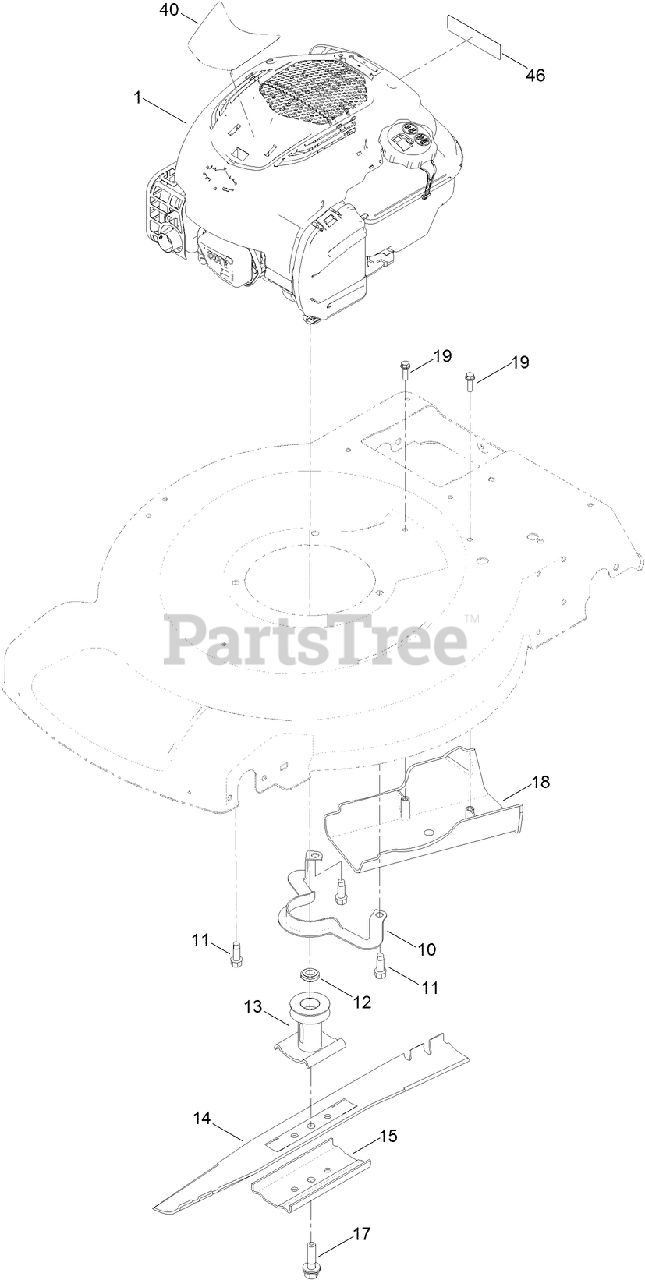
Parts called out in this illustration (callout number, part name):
10	GUIDE-BELT
11	SCREW-TAPTITE
12	SPACER-DRIVER
13	DRIVER-BLADE
14	BLADE-22 INCH
15	SUPPORT-BLADE
17	BOLT-BLADE
18	COVER-BELT
19	SCREW-HWH
40	DECAL-SHROUD
46	DECAL-ARRESTER, SPARK
